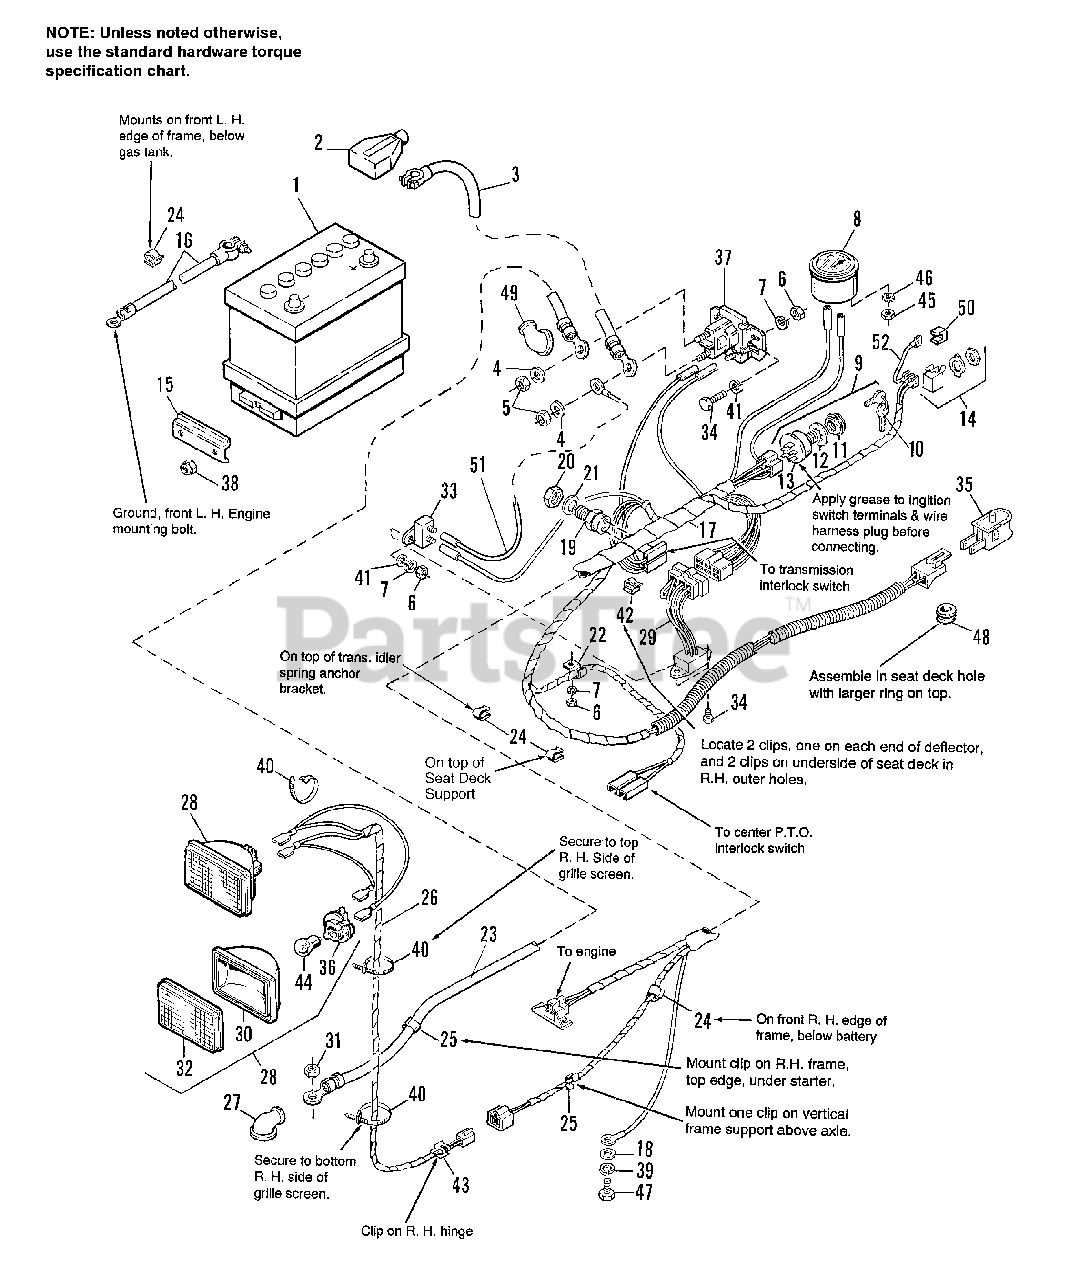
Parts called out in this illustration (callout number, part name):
1	BATTERY
2	INSULATOR, Battery Terminal
3	CABLE, Battery to Solenoid
4	LOCKWASHER, 5/16
5	NUT, Hex, 5/16-24
6	NUT, Hex, Full, 1/4-20
7	LOCKWASHER, 1/4
9	IGNITION SWITCH KIT
11	NUT, Adapter
12	LOCKWASHER, Int., 5/8
13	SWITCH, Ignition
14	SWITCH, Toggle
16	CABLE (Battery to Ground)
17	HARNESS ASSEMBLY
18	WASHER, 15/32
19	SWITCH, Interlock, Ball
21	WASHER, 9/16
22	CLIP, Cable
23	CABLE, Starter to Solenoid
24	CLIP, Tinnerman
25	CLIP, Tinnerman
26	WIRE ASSEMBLY
26	WIRE ASSEMBLY, Headlight
27	INSULATOR, Terminal Boot
28	HEADLIGHT ASSEMBLY
29	MODULE, Interlock
31	NUT, Hex
32	LENS, Clear
33	BREAKER, Circuit
34	CAPSCREW, Hex Hd, 1/4-20 x 3/4
35	SWITCH, Interlock, Seat
36	SOCKET, Bulb
37	SOLENOID, Starter
38	NUT, Elastic, 5/16-18
39	LOCKWASHER, 7/16
41	WASHER, 1/4 Special
42	CLIP, Wire
43	CLIP, Speed Cable
44	BULB
45	NUT, Hex, #10-32
46	LOCKWASHER, Ext. Tooth
47	CAPSCREW, Hex Hd, 7/16-14 x 1
48	BUSHING, Snap
49	COVER, Terminal, Solenoid
50	ADAPTOR, Wire Terminal
51	WIRE ASSEMBLY, Solenoid to Circuit Breaker
52	WIRE, Jumper, Headlight Switch
